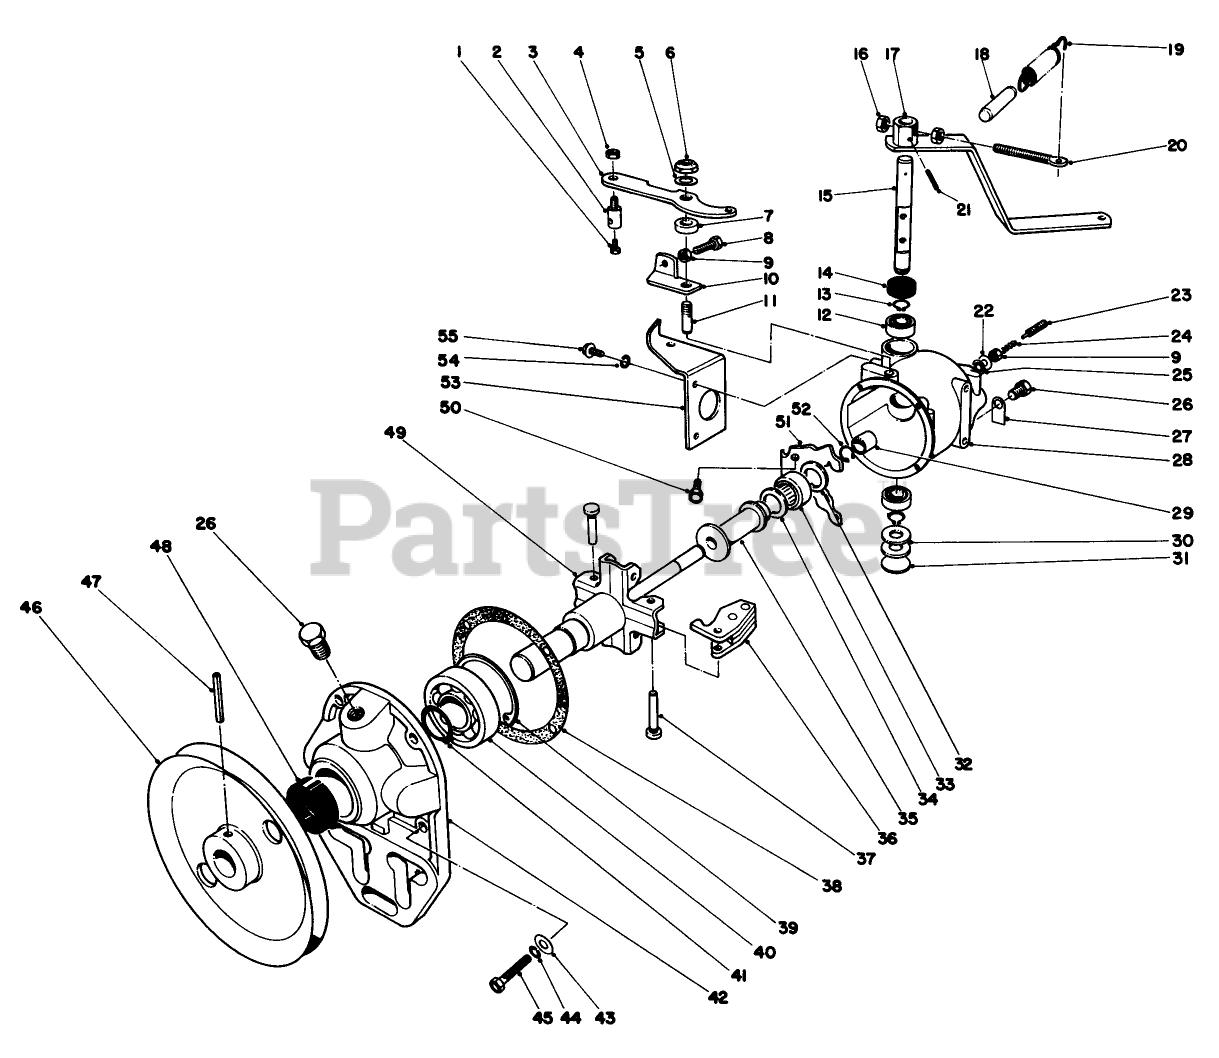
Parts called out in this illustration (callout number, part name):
1	SCREW-HH
2	SWIVEL
3	Speed Change Lever
4	NUT-LOCK, NI
5	WASHER
6	LACKNUT
7	Spacer
8	SCREW-HH
9	NUT-HEX
10	Stop Bracket
12	BALL BRG
13	EXT SNAP RING
14	OIL SEAL
15	Rocker Shaft
16	NUT-HEX
17	THROTTLE LEVER ASM
18	FORCED IDLE PLUG
19	SPRING
20	EYESCREW
21	PIN-ROLL
22	Shim Washer
23	BUMPER SCREW
24	BUMPER SPRING
25	SEALING WASHER
26	PIPE PLUG
27	OIL LEVEL TAG
29	DRIVE SHAFT BUSHING
30	WASHER
31	WELCH PLUG
32	THRUST WASHER
33	THRUST BEARING
34	THRUST WASHER
35	THRUST SLEEVE
36	WEIGHT ASM
37	WEIGHT PIN
38	GASKET
39	INT BEVELED
40	BEARING-BALL
41	RETAINING RING
42	FLANGE
43	WASHER-FLAT
44	WASHER-LOCK
45	10-24 X 7/8 IND HD SC
46	Pulley
47	PIN-SPRING
48	OIL SEAL
49	SPIDER & SHAFT ASM
50	MACHINE SCREW
52	RETAINING RING
53	Bracket
54	WASHER-LOCK
55	SCREW
